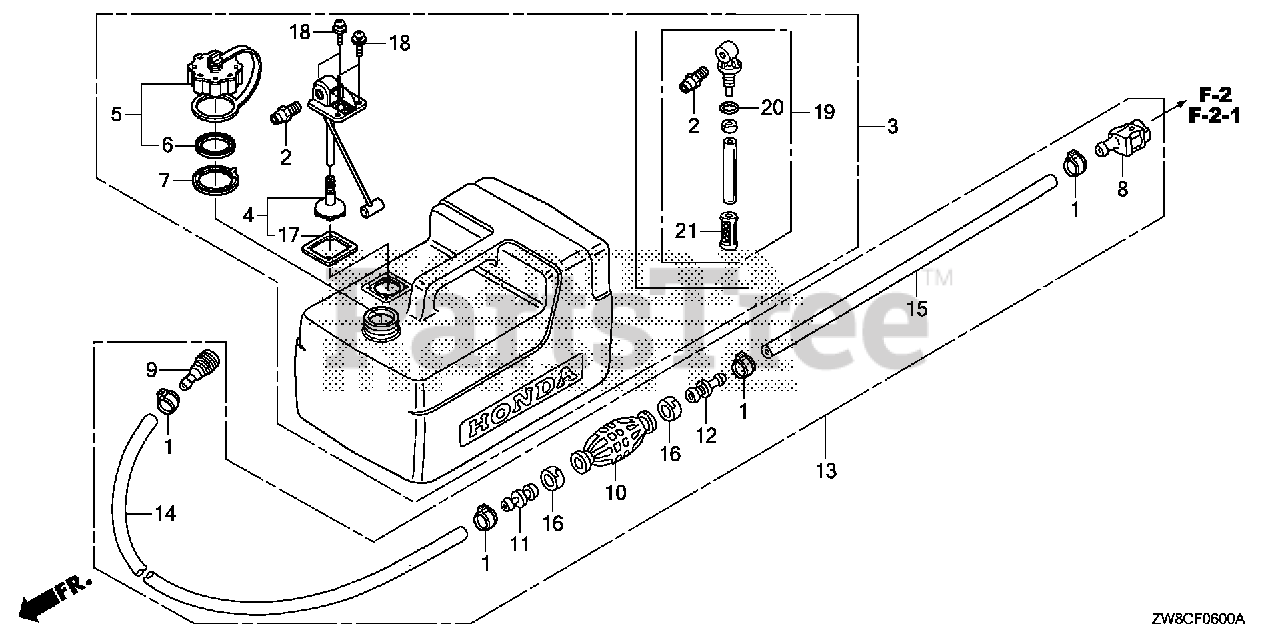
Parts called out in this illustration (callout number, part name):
1	CLAMP, FUEL TUBE (14.0) (CONNECTOR TYPE)
2	FITTING, QUICK DISCONNECT Use from Frame SN 1205705.
3	TANK, FUEL (12L)
4	FILTER KIT, FUEL
6	GASKET, FUEL CAP
7	RETAINER, PRESSURE RELIEF
8	CONNECTOR ASSY., FUEL (A)
9	CONNECTOR, FUEL (CONNECTOR TYPE)
10	BULB, PRIMER
11	VALVE, IN.
12	VALVE, OUTLET
13	TUBE ASSY., FUEL TANK
14	TUBE, FUEL LONG (7.3X2000)
15	TUBE, FUEL SHORT
16	BAND, TUBE CLIP (20MM)
17	GASKET, FUEL PICK-UP
18	BOLT-WASHER (5MM) (SEAL)
19	JOINT ASSY., FUEL
20	O-RING Use from Frame SN 1300962.
21	FILTER, FUEL
